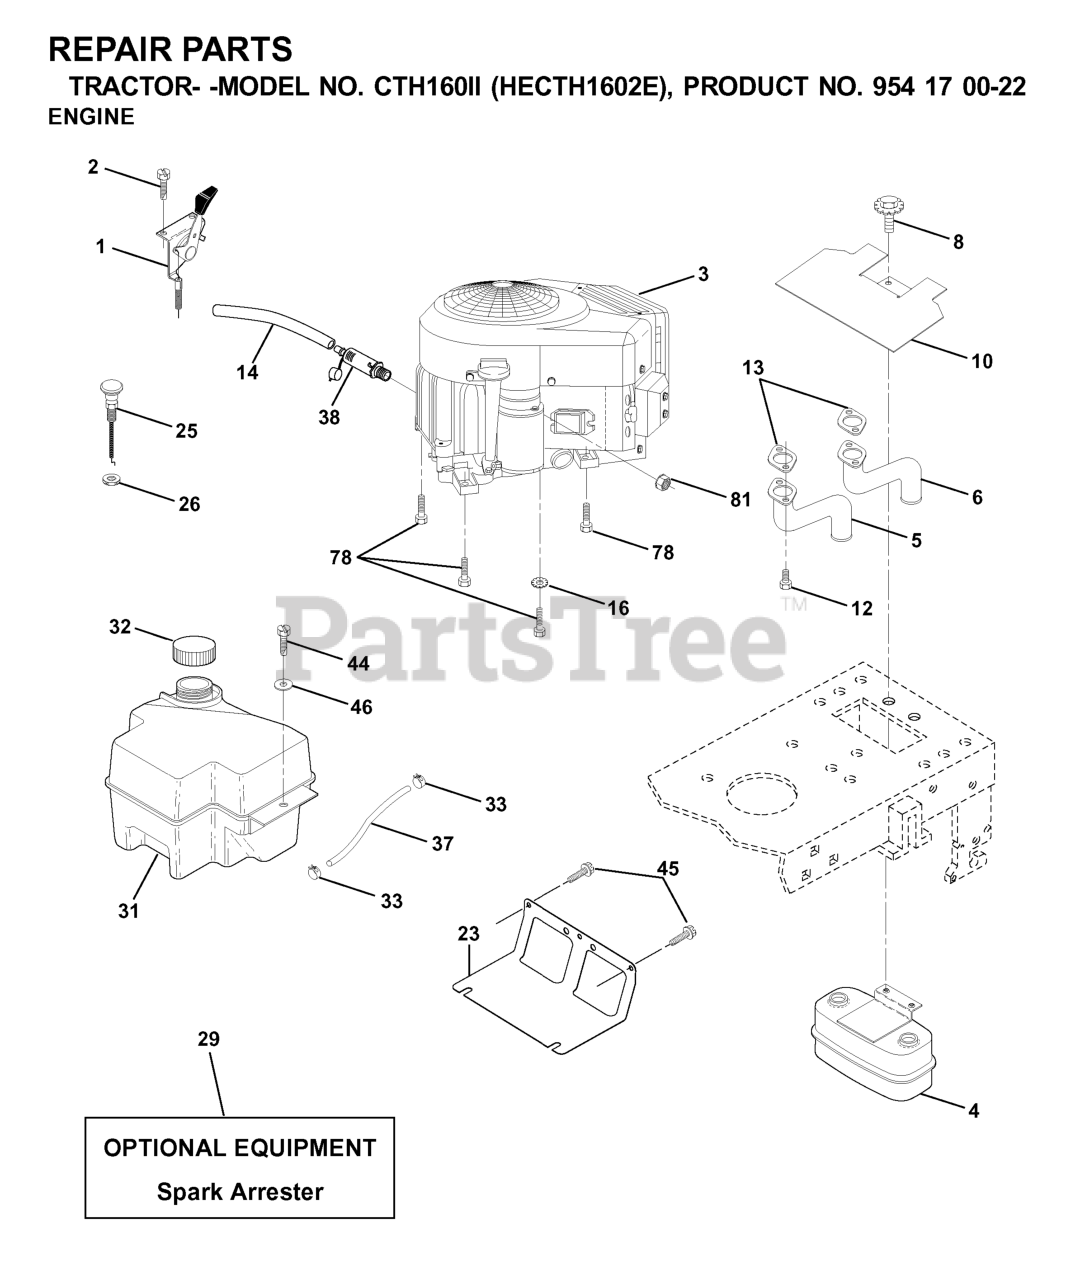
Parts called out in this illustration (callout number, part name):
1	CONTROL, THROTTLE
2	SCREW LT
4	MUFFLER.TWIN.CYL.LOW.TONE
5	TUBE ASSY EXH LH
6	TUBE ASSY EXH RH
8	BOLT.5/16-18UNCX3/4 W/SEMS.BLK
10	SHIELD HEAT LT
14	TUBE, DRAIN OIL ASM.
16	LOCKWASHER
23	SHIELD.BROWNING.DBR.GUARD
25	CONTROL, CHOKE
26	Nut Keps 3/8 - 24 UNF
29	KIT.SPARK ARRESTOR 794945 B&S
31	TANK, 2GAL
32	FUEL CAP
33	HOSE CLAMP
37	LINE.FUEL.20
38	PLUG, OIL DRAIN EASY
44	SCREW HEXWSHR 1/4-20X3/4
45	SCREW, 3/8-16X3/4
78	SCREW.3/8-16
81	NUT
